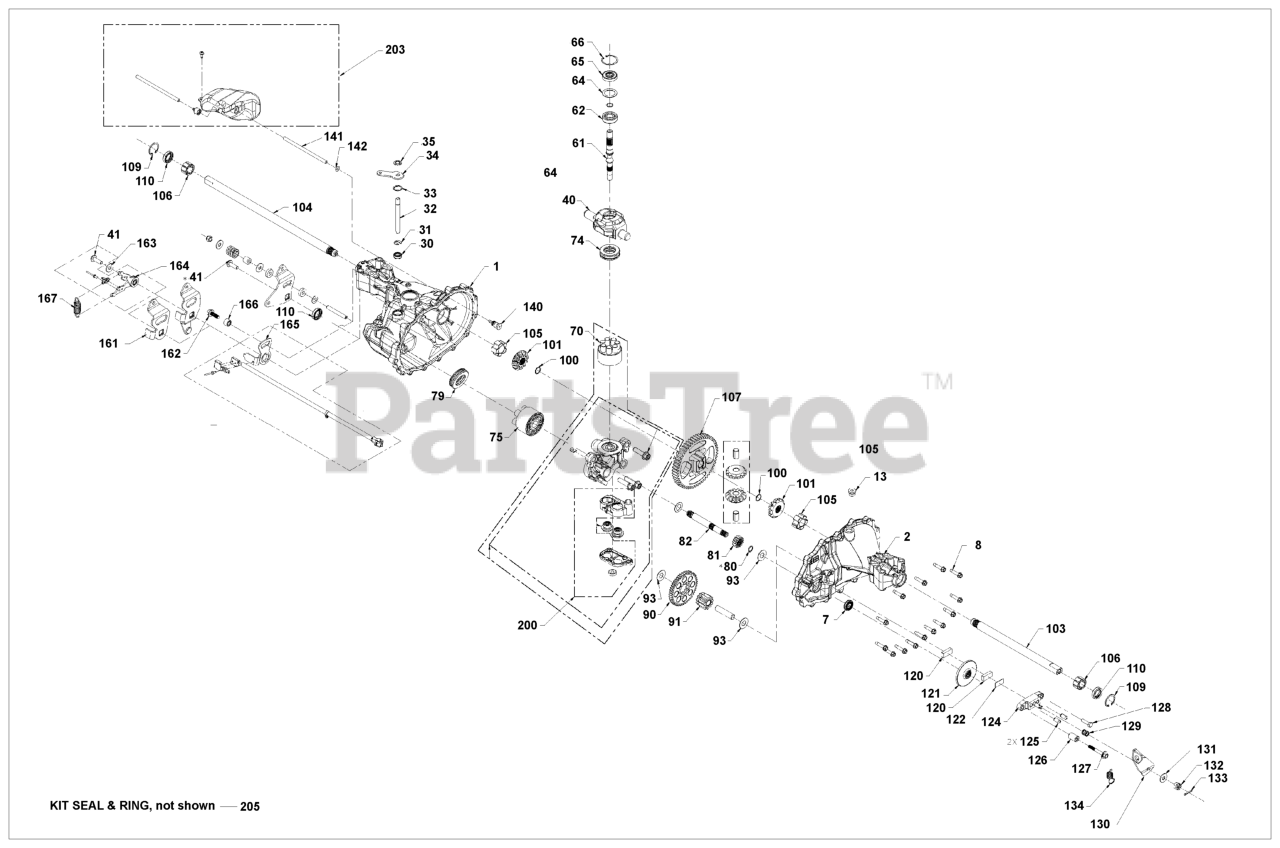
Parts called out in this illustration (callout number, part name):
62	BALL BEARING
75	KIT CYLINDER #70331
80	SEAL LIP
109	RETAINER.RING.INT.AXLE
122	PUCK PLATE 44134
125	BRAKE PIN 44127
128	BOLT W/NYLOCK 44433
131	WASHER FLAT
